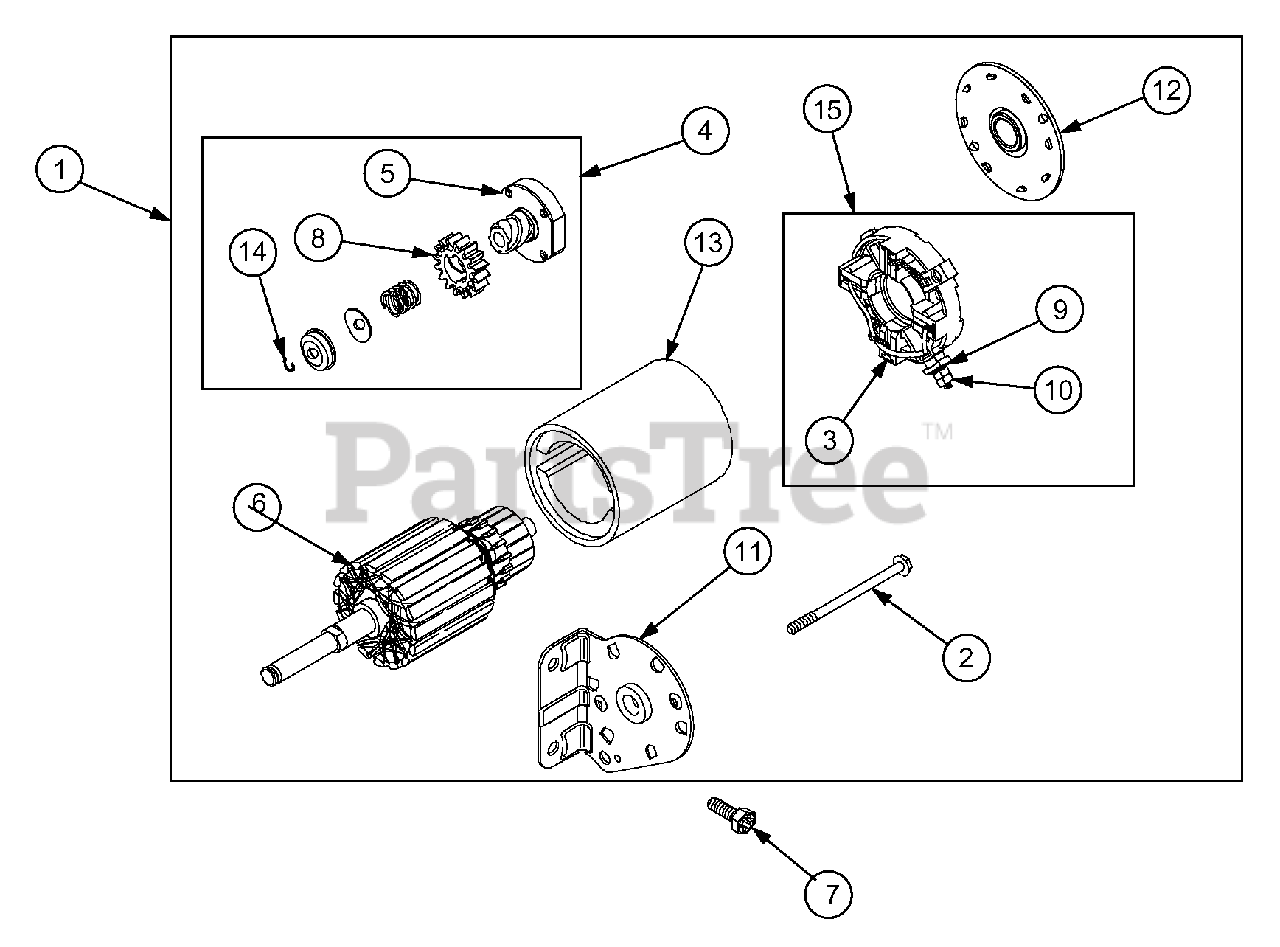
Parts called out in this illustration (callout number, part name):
1	Motor, Starter
4	Drive, Starter
5	Clutch, Drive
6	Armature, Starter
7	Screw, Drive Cap
8	Gear, Pinion
9	Nut (Brush Retainer)
10	Nut (Brush Retainer)
11	Cap, Drive
13	Housing, Starter
14	Ring, Retaining
15	Retainer, Brush
